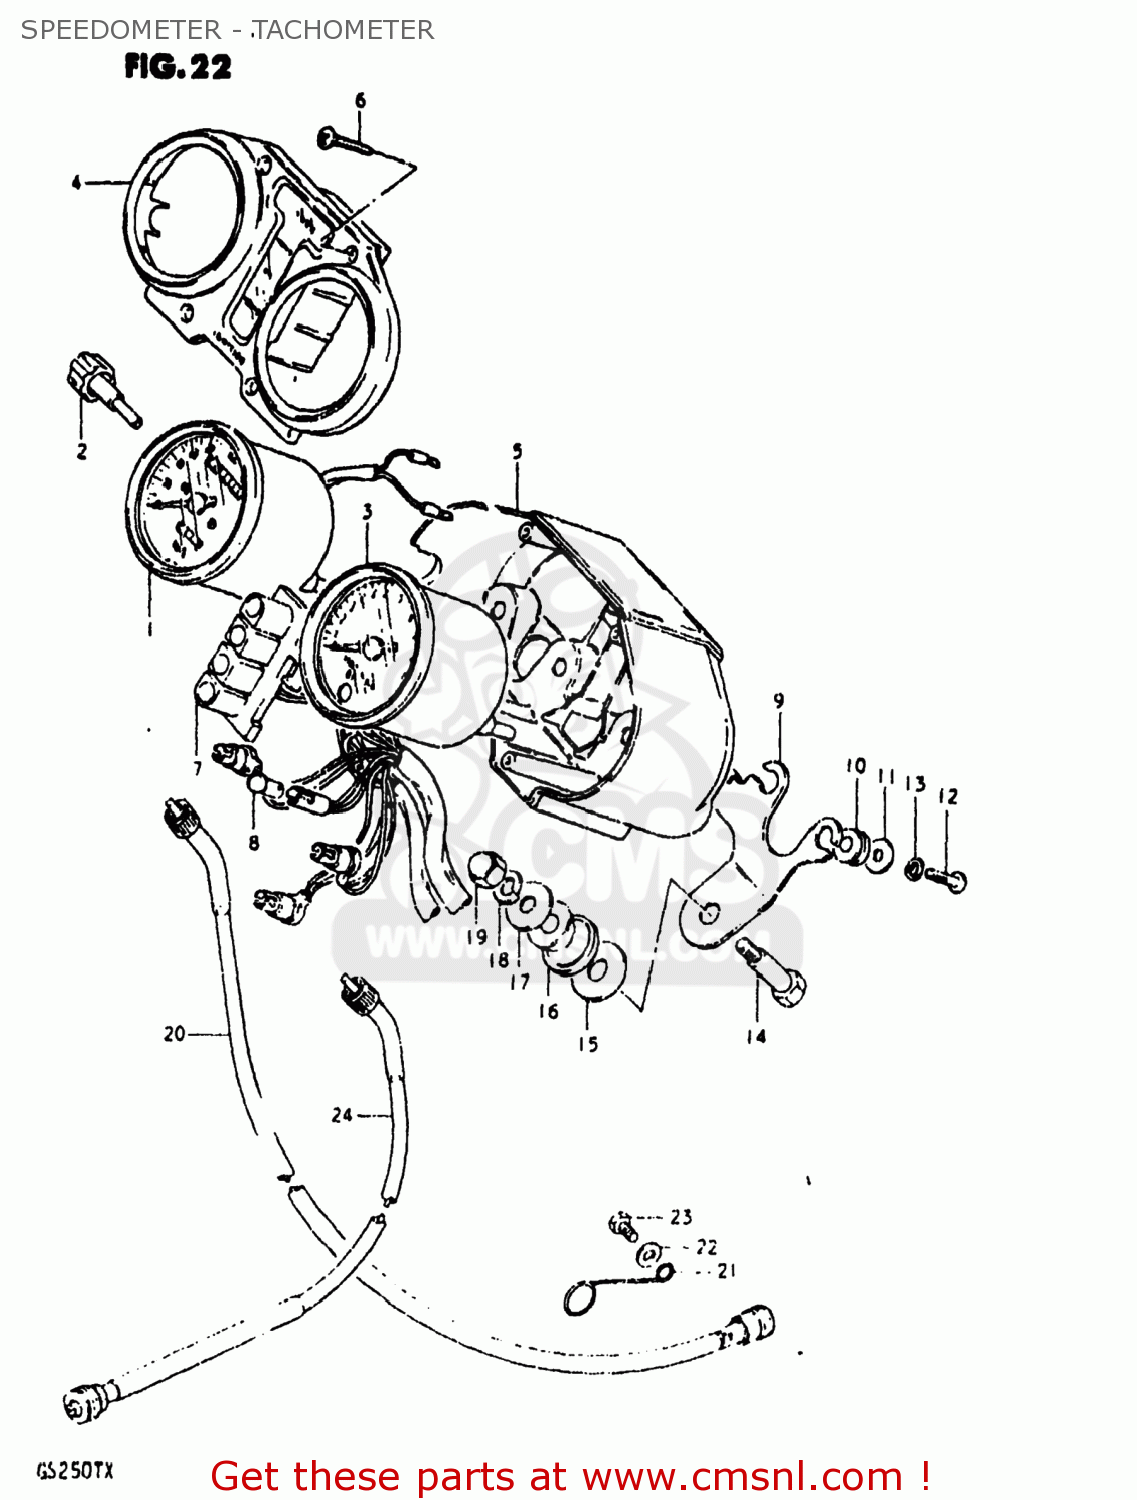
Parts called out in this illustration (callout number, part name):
1	SPEEDOMETER ASSEMBLY
2	KNOB,TRIP METER
3	TACHOMETER
4	HOOD,METER
5	VISOR,LWR
6	SCREW
7	SOCKET,METER
8	BULB(12V3.4W,T10)
9	BRACKET,METER
10	CUSHION
11	WASHER,METER
12	SCREW
13	LOCK WASHER
14	BOLT
15	WASHER
16	CUSHION,METER
17	WASHER(8.5X23X1.2)
18	LOCK WASHER
19	NUT
20	CABLE ASSEMBLY,SPEEDOMETER
21	GUIDE,SPEEDOMETER CABLE
22	WASHER
23	BOLT, UPPER
24	CABLE ASSEMBLY,TACHOMETER
